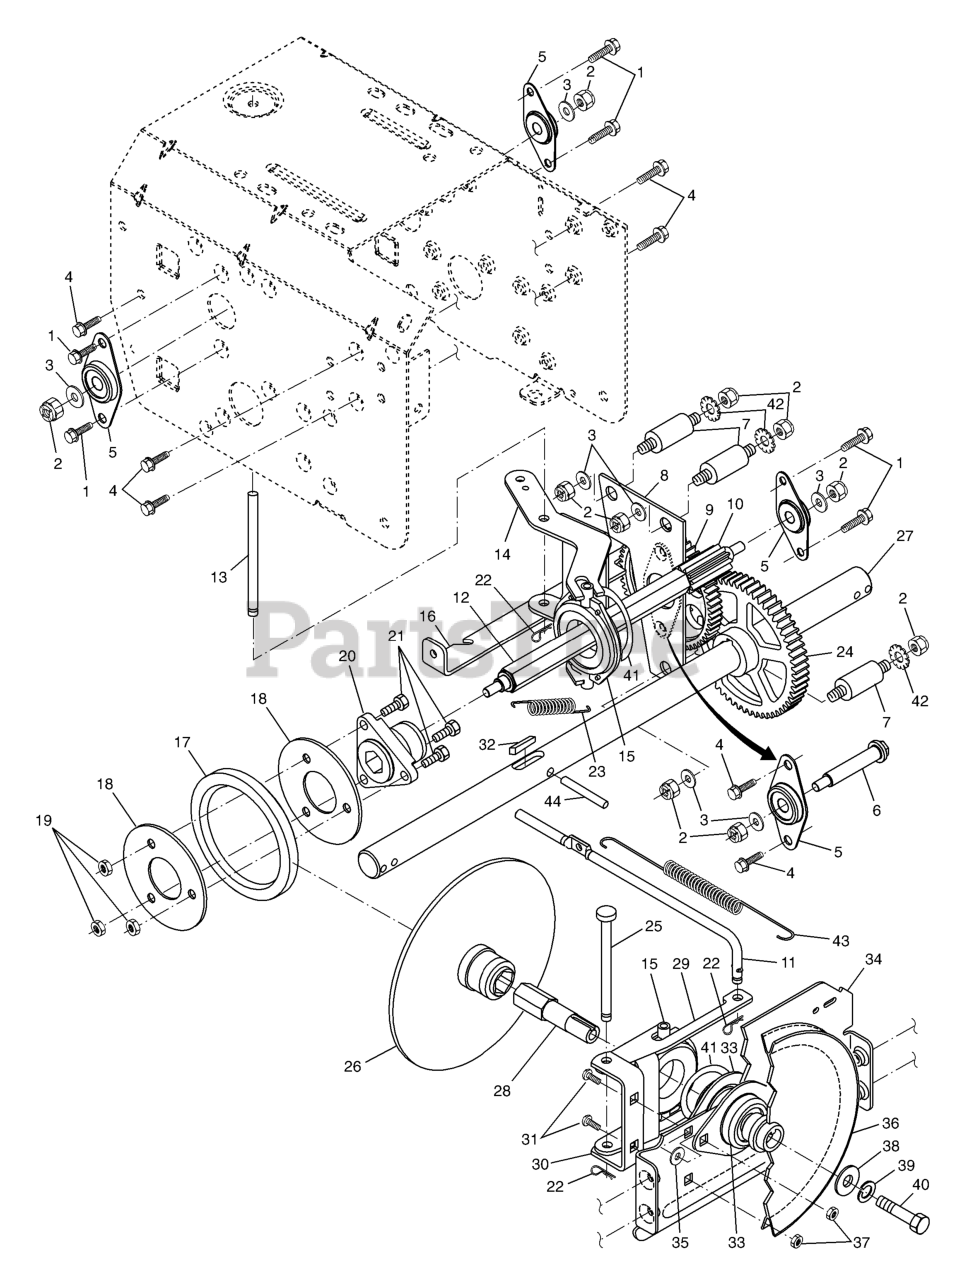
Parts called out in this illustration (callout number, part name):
2	NUT.71038.31-18.HEX.NYLOCK
3	WASHER.20X8.5
4	Screw, Hex Head 5/16-18 x 1/2
5	BEARING, FLANGE
6	SHAFT, AUXILIARY
7	SPACER, PLATE
8	AUXILLARY PLATE
9	GEAR, INTERMEDIATE
10	GEAR, PINION
11	ROD.CLUTCH.YELLOW.ZINC
12	SHAFT.HEX.LONG
13	PIN, PIVOT
14	LEVER, SPEED CONTROL
15	TRUNNION BEARING ASSY
16	BRACKET, PIVOT, SHIFT
17	RING, RUBBER WHEEL
18	PLATE.RUBBER.WHEEL
19	NUT.CENTERLOCK.5/16-
20	HUB, RUBBER WHEEL
21	BOLT
22	RETAINER CLIP PM
23	SPRING, BIAS
24	GEAR, AXLE (58T)
25	PIN, PIVOT LEVER
26	DRIVE PLATE WELDMENT
27	SHAFT.AXLE.16".POWER.STEER.SNO
28	SHAFT.HEX.SHORT
29	LEVER.SHIFTER.PLATE.BLACK
30	BRACKET, SHIFTER SUPPORT
31	BOLT
32	KEY, SQUARE 1/4 X .875
33	BEARING FLANGE
34	PLATE.DRIVE.MOUNTING.BLACK
35	SPACER, BEARING
36	PULLEY.TRACTION.7.75
37	NUT.FLANGE.5/16
38	WASHER, FLAT
39	WASHER.LOCK.HVY.HLCL.SPR.5/16
40	Screw, Hex Head 5/16-18 x 3/4
41	RETAINING RING (2 2)(3 2)
42	WASHER EXT TOOTH LOCK 5/16
43	SPRING.RETURN
44	PIN.ROLL.3/16
